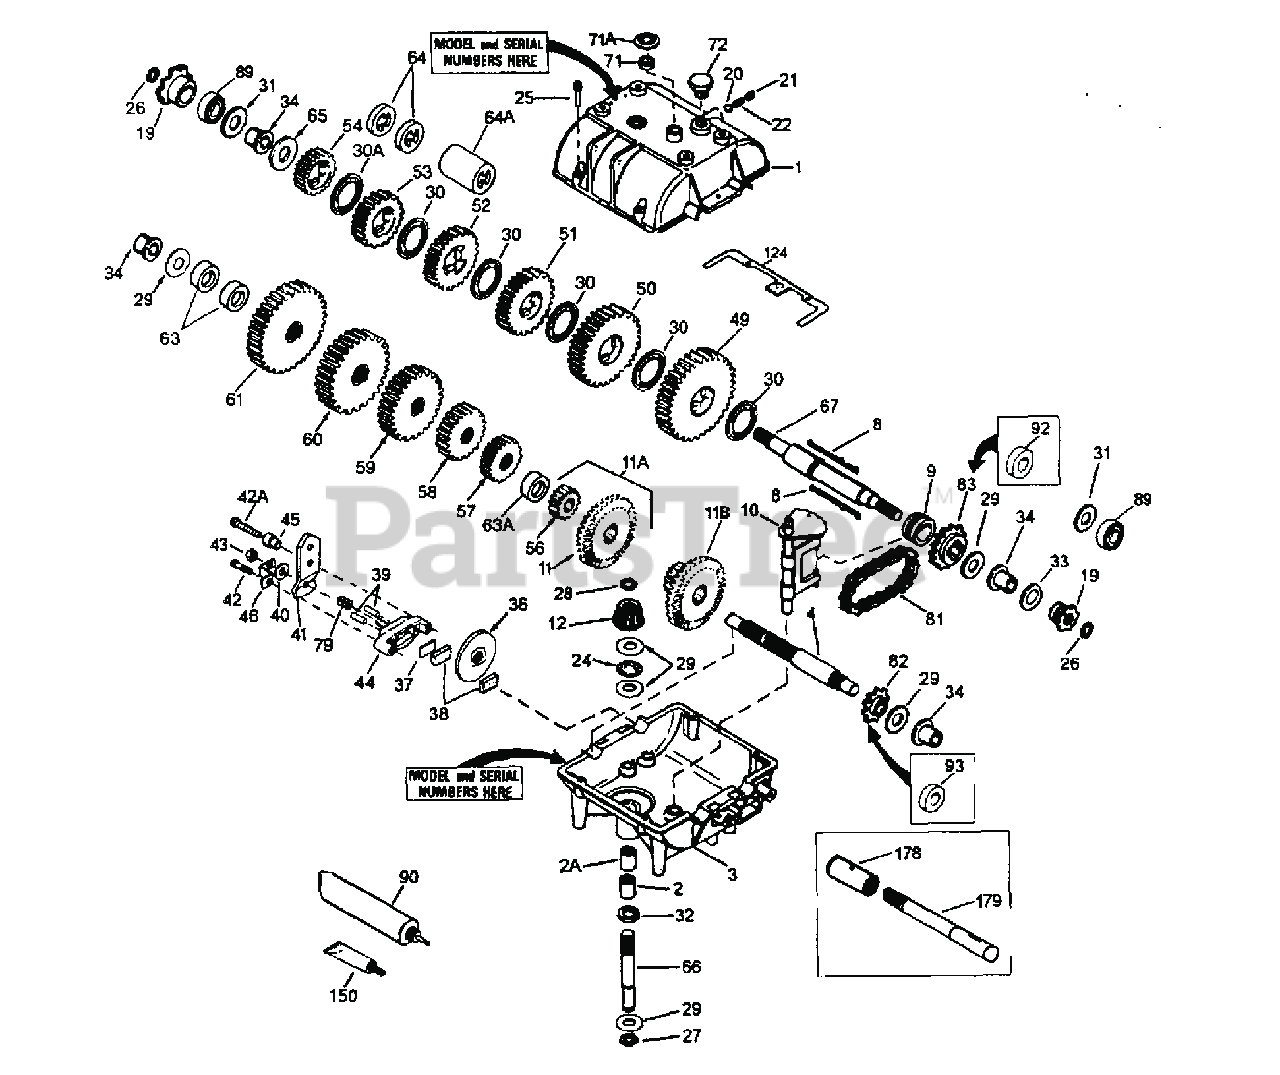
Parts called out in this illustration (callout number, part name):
1	Case, Transmisson
2	Needle Bearing Grease Spec
2A	BEARING, NEEDLE
3	Case, Transmission
8	Shift Key
9	COLLAR, SHIFT
10	Shift Rod & Fork
11	Gear, Bevel (42 teeth)
12	Bevel Pinion (14 teeth-steel)
20	Steel Ball, 5/16" dia.
21	SET SCREW, 3/8-16 X 3/8(1)
22	SPRING(1)
24	BEARING, THRUST(1)
25	Screw, Flanged Hex Hd Thread, 1/4-20 x 1-1/4"
27	RING, RETAINING
28	RING, RETAINING(1)
29	WASHER, THRUST(3)
30	WASHER, THRUST(4)
32	"O" RING(5)
34	BUSHING, FLANGED
49	Gear, Spur (37 teeth)
50	Gear, Spur (35 teeth)
51	Spur Gear (32 teeth-steel)
52	Gear, Spur (30 teeth)
53	Gear, Spur (25 teeth)
56	Spur Gear (12 teeth-steel)
57	Gear, Spur (15 teeth)
58	Spur Gear (18 teeth-steel)
59	Gear, Spur (20 teeth)
60	Gear, Spur (25 teeth)
65	WASHER, THRUST(1)
66	Input Shaft (3-11/16" long)
67	Shifter & Brake Shaft
71	SEAL, SQUARE CUT
72	Threaded Plug (Shipping only, not used)
81	CHAIN, ROLLER(NO. 41 CHAIN, 24 LINKS)(1)
82	SPROCKET(9 TEETH)(1)
83	Sprocket (18 teeth)
90	Grease (32 oz. bottle Bentonite grease)
150	Gasket Eliminator (Loctite #515)
178	Coupling
179	Connector Shaft
